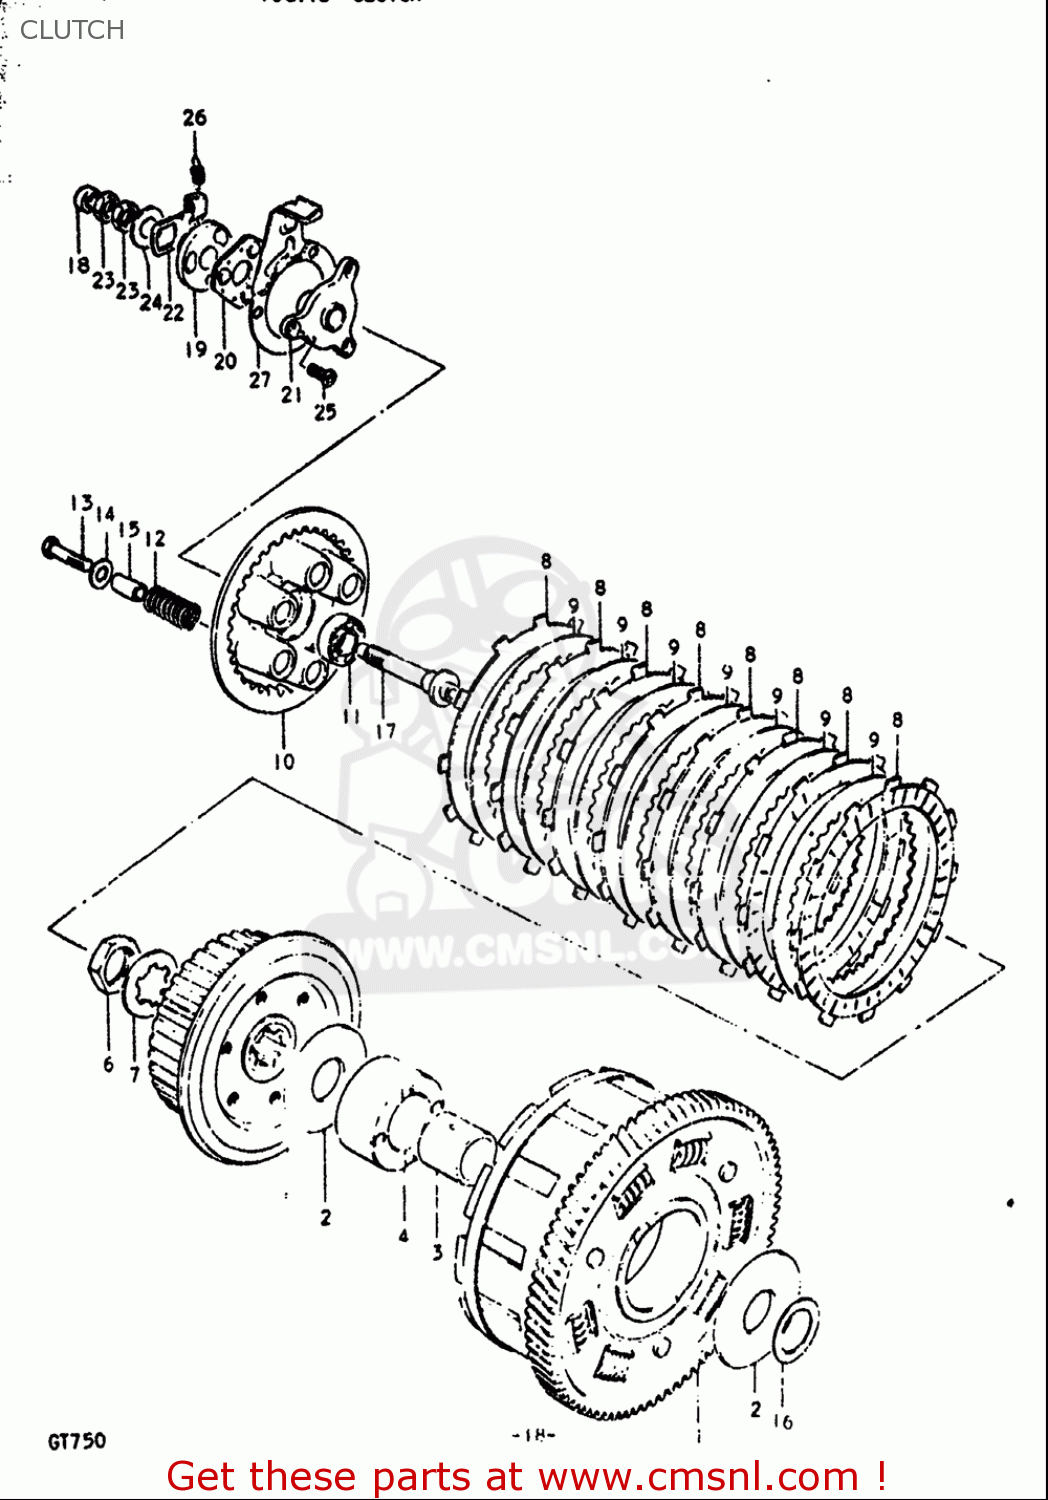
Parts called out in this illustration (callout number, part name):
2	WASHER
4	SPACER
6	NUT
7	WASHER,LOCK
8	PLATE,CLUTCH DRIVE (NAS)
9	PLATE,CLUTCH DRIVEN(T:2.0) (NAS)
12	SPRING
13	BOLT
14	WASHER
16	SHIM(25X36X0.5)
18	OIL SEAL (10X17X5.5)
20	BALL,CLUTCH RELEASE
23	NUT
25	SCREW
26	SPRING
